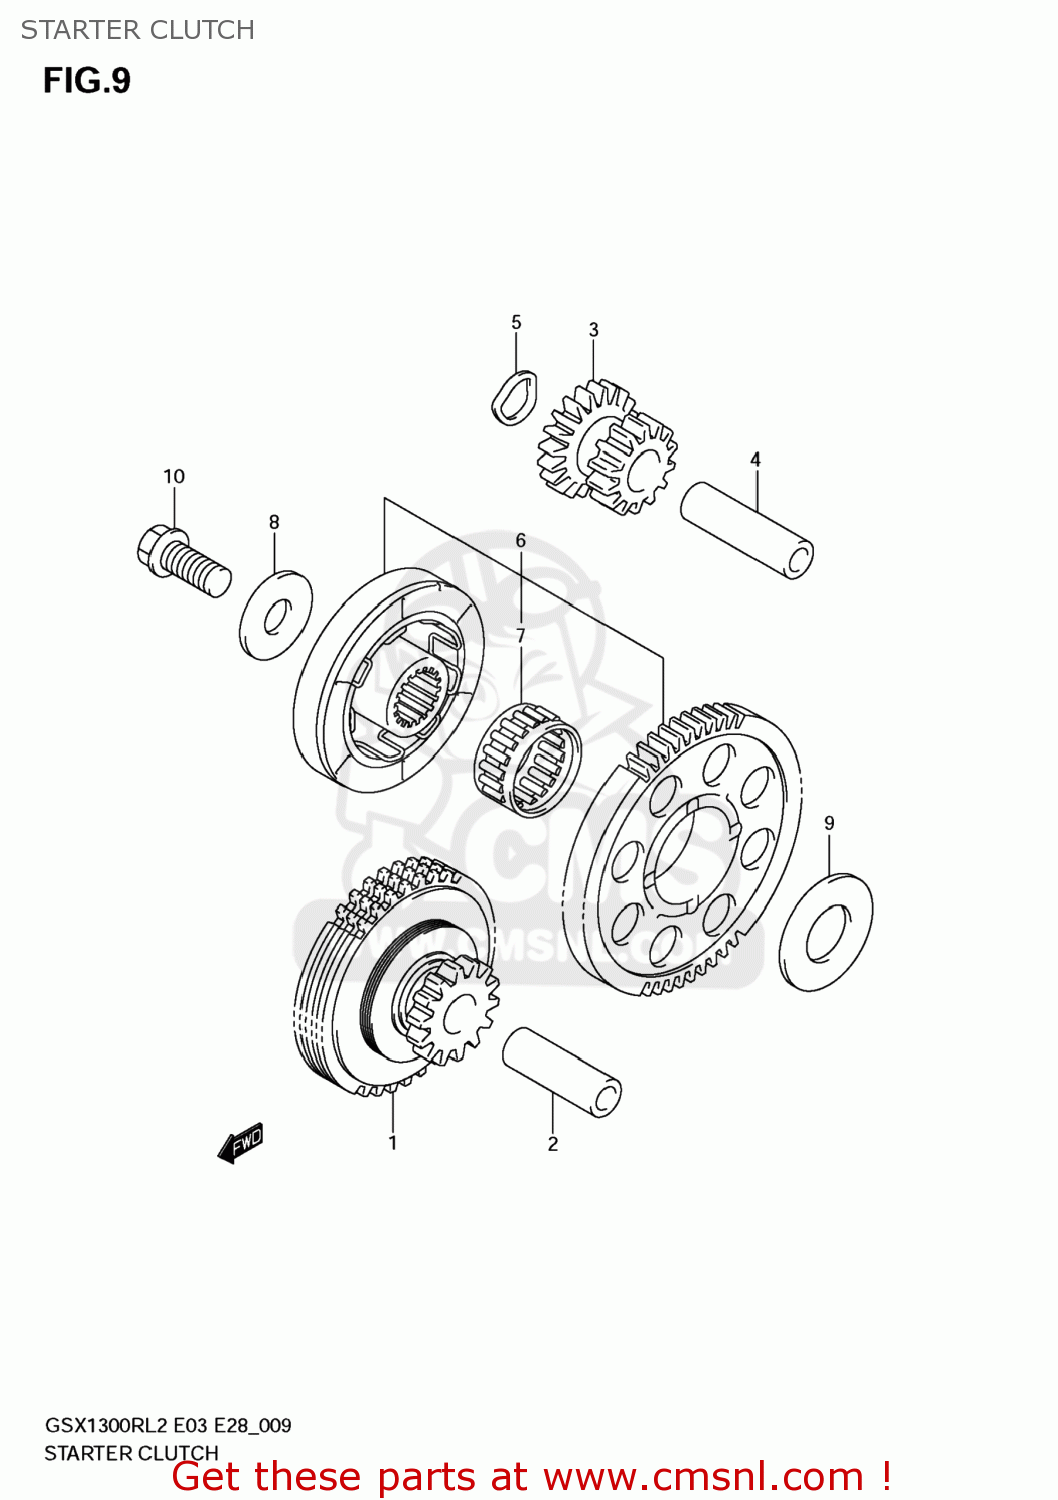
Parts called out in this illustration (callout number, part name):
1	LIMITER ASSY,START ID GR NO.1
2	PIN,STARTER IDLE GEAR NO.1
3	GEAR,STARTER IDLE NO.2
4	PIN ,PISTON
5	WASHER
6	CLUTCH SET,STARTER
7	BEARING(28X34X16.8)
8	WASHER
9	WASHER
10	BOLT(10X23)
